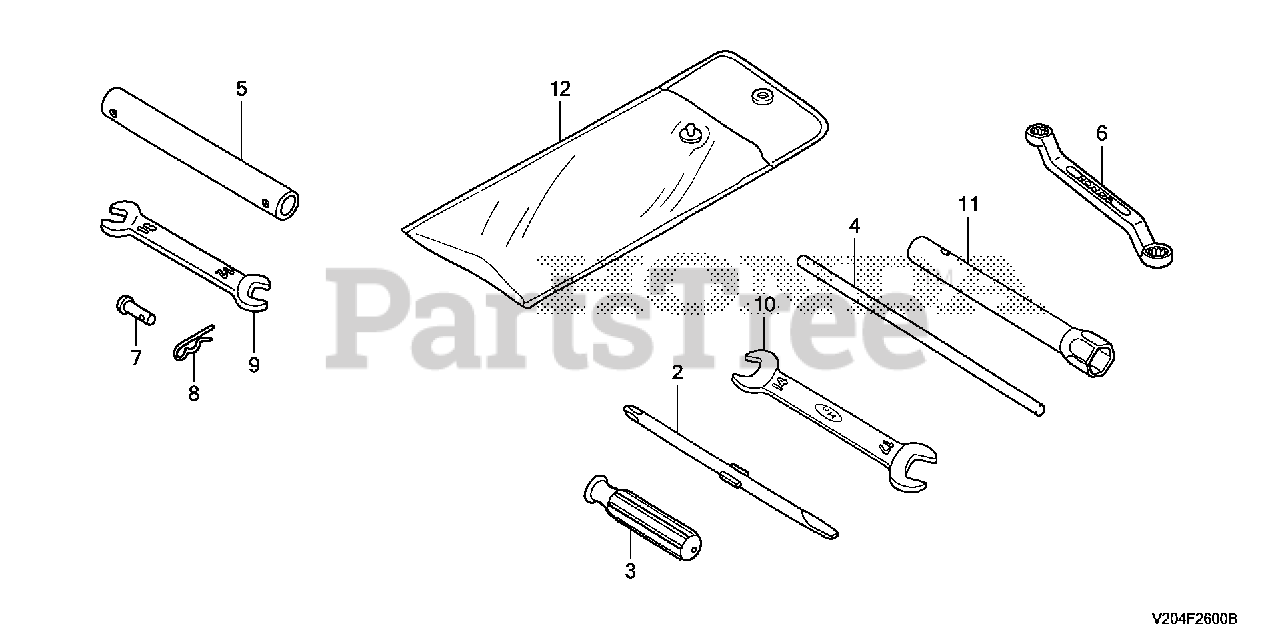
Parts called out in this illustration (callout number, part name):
1	TOOL KIT (NOT AVAILABLE)
2	SCREWDRIVER (NO.2 PHILLIPS -)
3	GRIP
4	HANDLE, BOX WRENCH
5	PIPE, BOX WRENCH EXTENSION
6	WRENCH, EYE (10X12)
7	PIN, ROLLER ARM (8X22)
8	PIN, LOCK (8MM)
9	SPANNER (10X12)
10	SPANNER (14X17)
11	WRENCH, BOX (P21)
12	BAG, TOOL (230MM)
